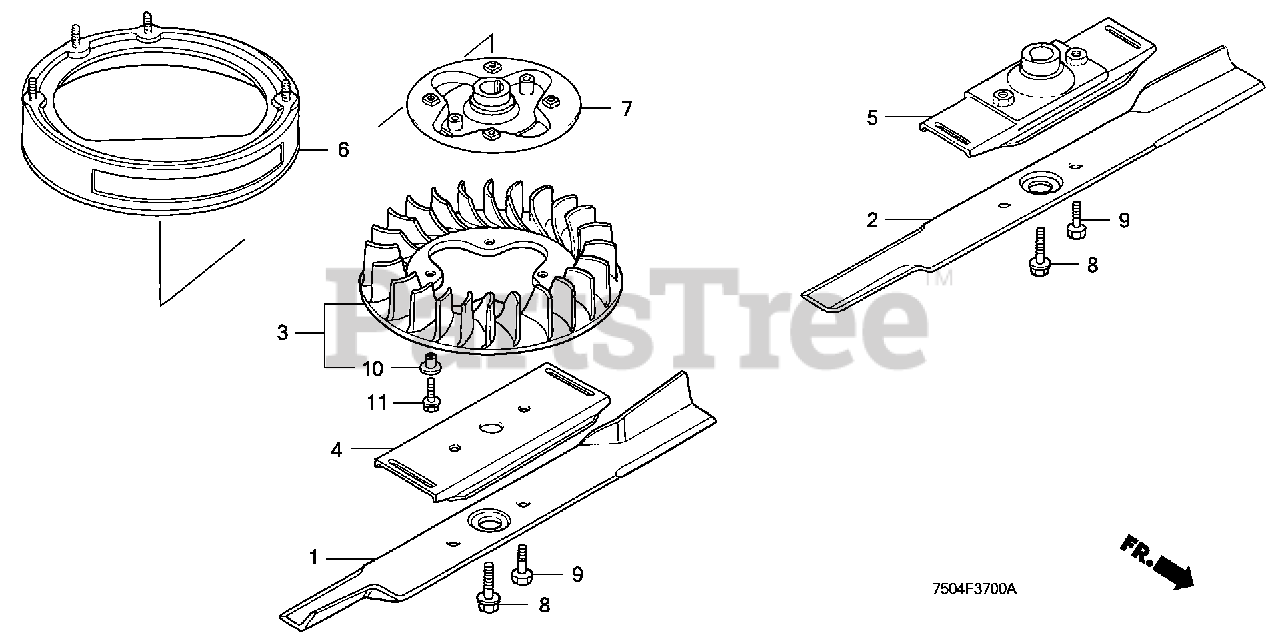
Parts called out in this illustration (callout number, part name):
1	BLADE, R. ROTARY
2	BLADE, L. ROTARY
3	FAN ASSY., DISCHARGE
4	HOLDER, BLADE
5	HOLDER, BLADE
6	GUARD, R. FAN
7	HOLDER, BLADE
8	BOLT, HEX. (10X25)
9	BOLT, HEX. (10X20)
10	WASHER (6X20)
11	BOLT, FLANGE (6X16)
